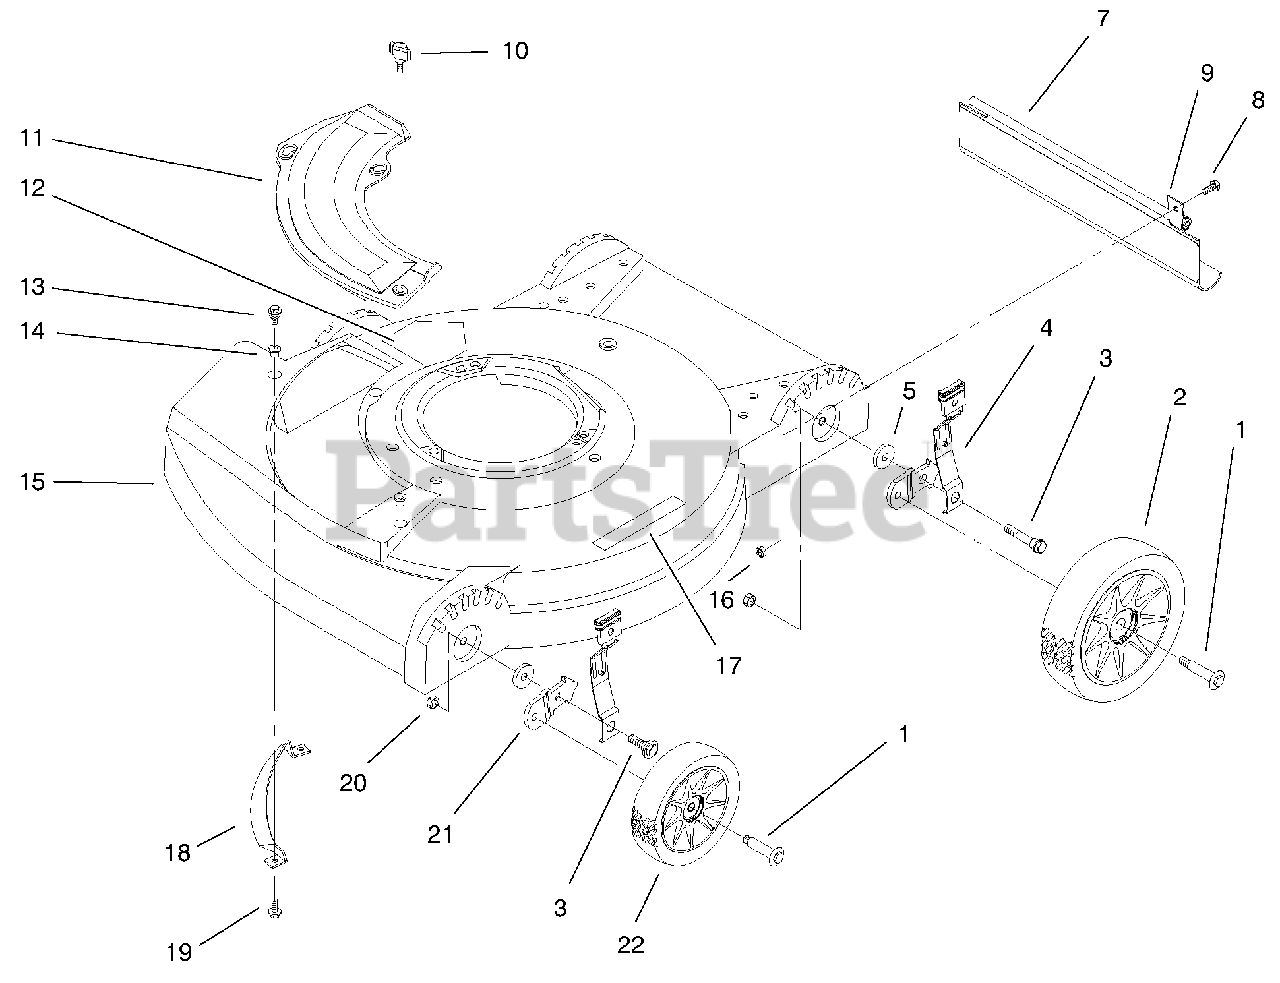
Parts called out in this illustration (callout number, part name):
1	Bolt-Wheel
2	ASM-Wheel & Tire
3	Bolt-Ajustment
4	Knob & Spring
7	Shield-Trailing
8	Screw-HH
9	Clamp-Rod
10	Knob-Cover Plate
11	Plate-Cover
12	Decal-Danger
13	Screw-Sems
14	Grommet-Plastic
15	Housing-Commercial 21"
16	Nut-Lock
17	Decal-Warning
18	Toe Bar 21
19	Screw-HWH
20	Nut-Lock
21	Bracket-Height
22	Wheel & Tire
